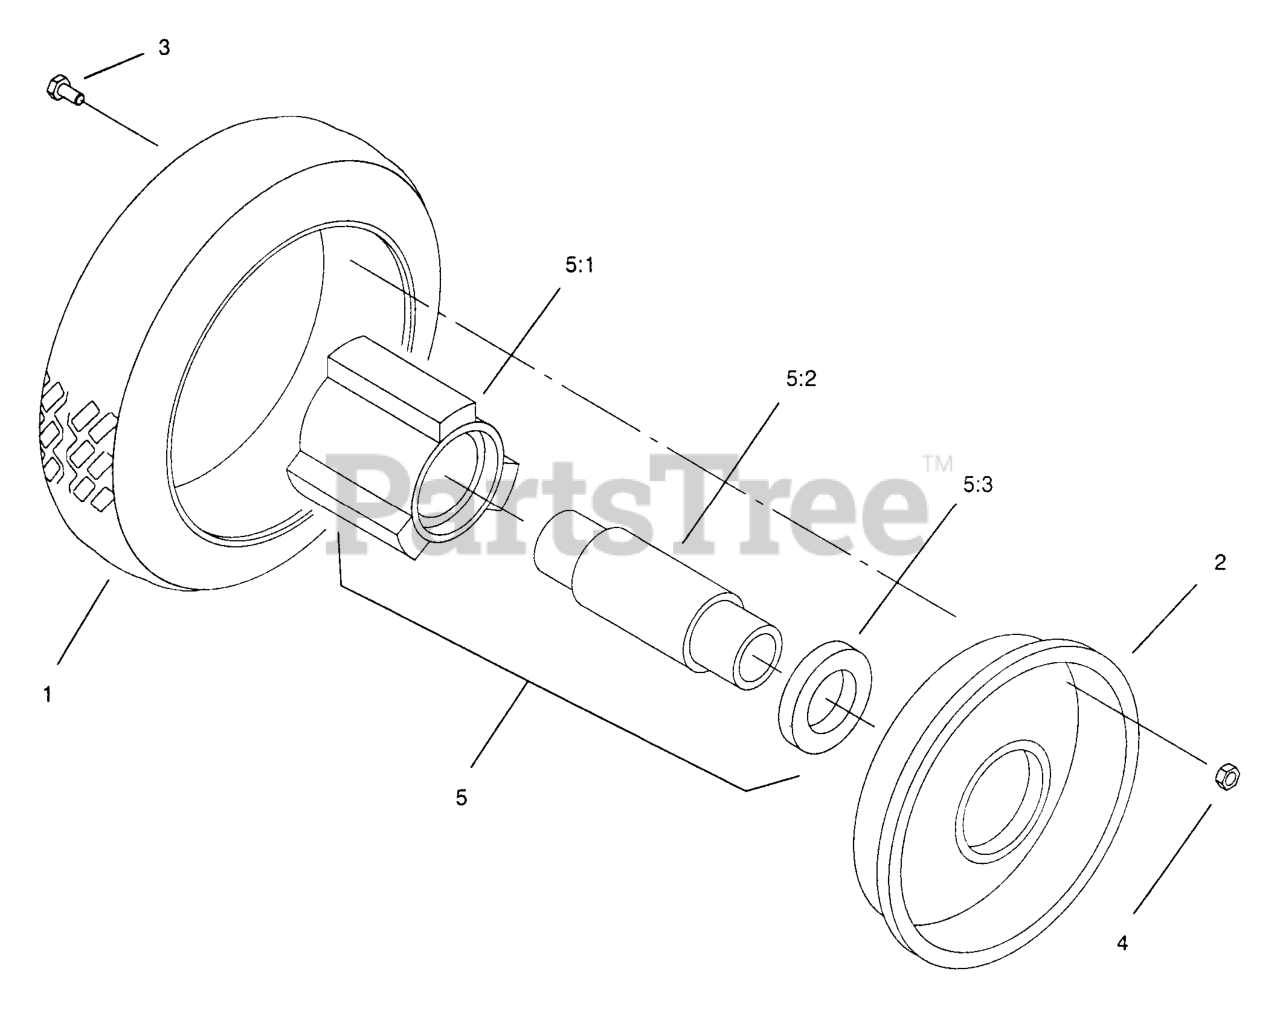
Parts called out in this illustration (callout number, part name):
3	SCREW-HH
4	NUT-LOCK, NI
5	Hub & Bearing Asm
5:1	HUB-BEARING
5:2	SPACER-BEARING
5:3	BEARING-WHEEL
